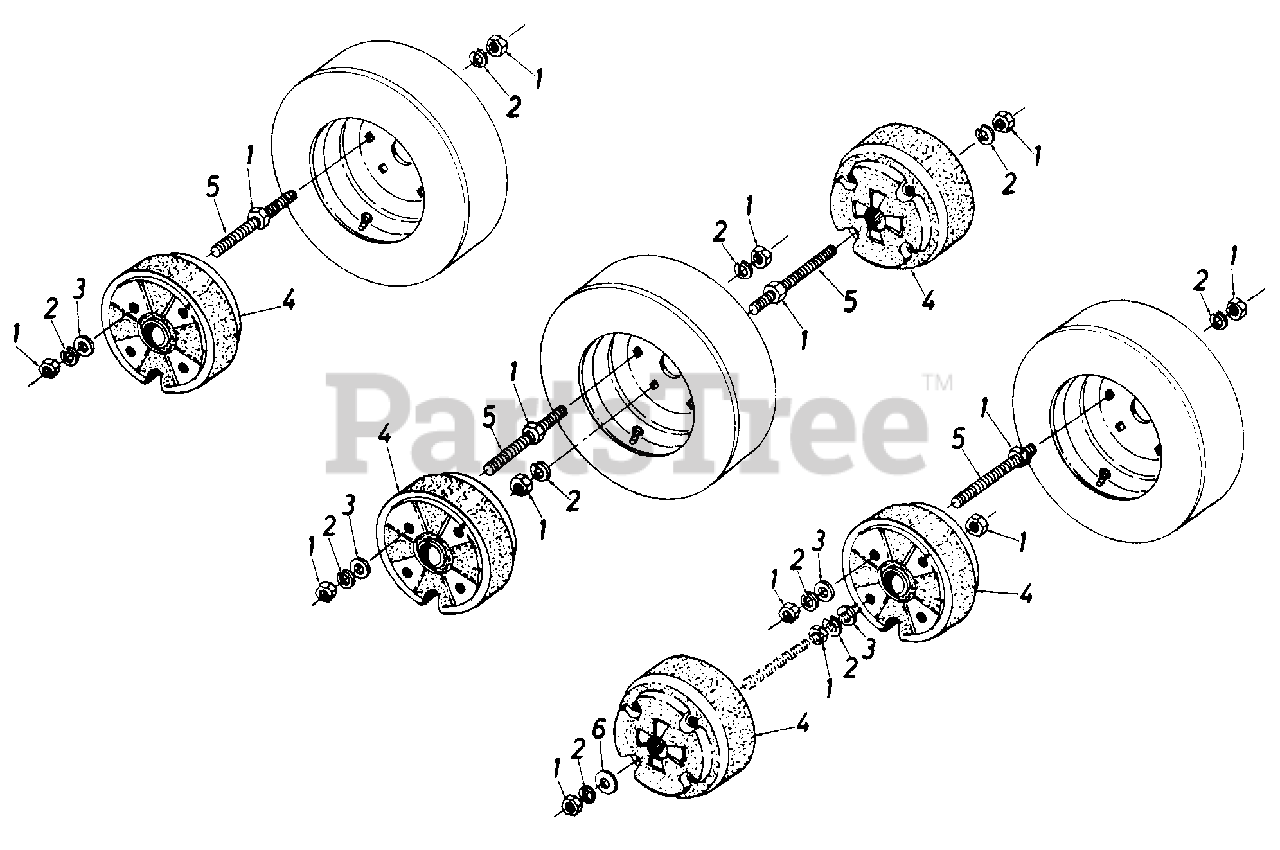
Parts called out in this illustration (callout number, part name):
1	Hex Nut 1/2-13 Thd.
2	Lock Washer 1/2" I.D.
3	Flat Washer .53" I.D. x .93" O.D.
4	Wheel Weight
5	Rod Threaded 1/2-13 x 9.50 Lg.
6	Fl.Wash. .50" I.D. x 2.00" O.D.
